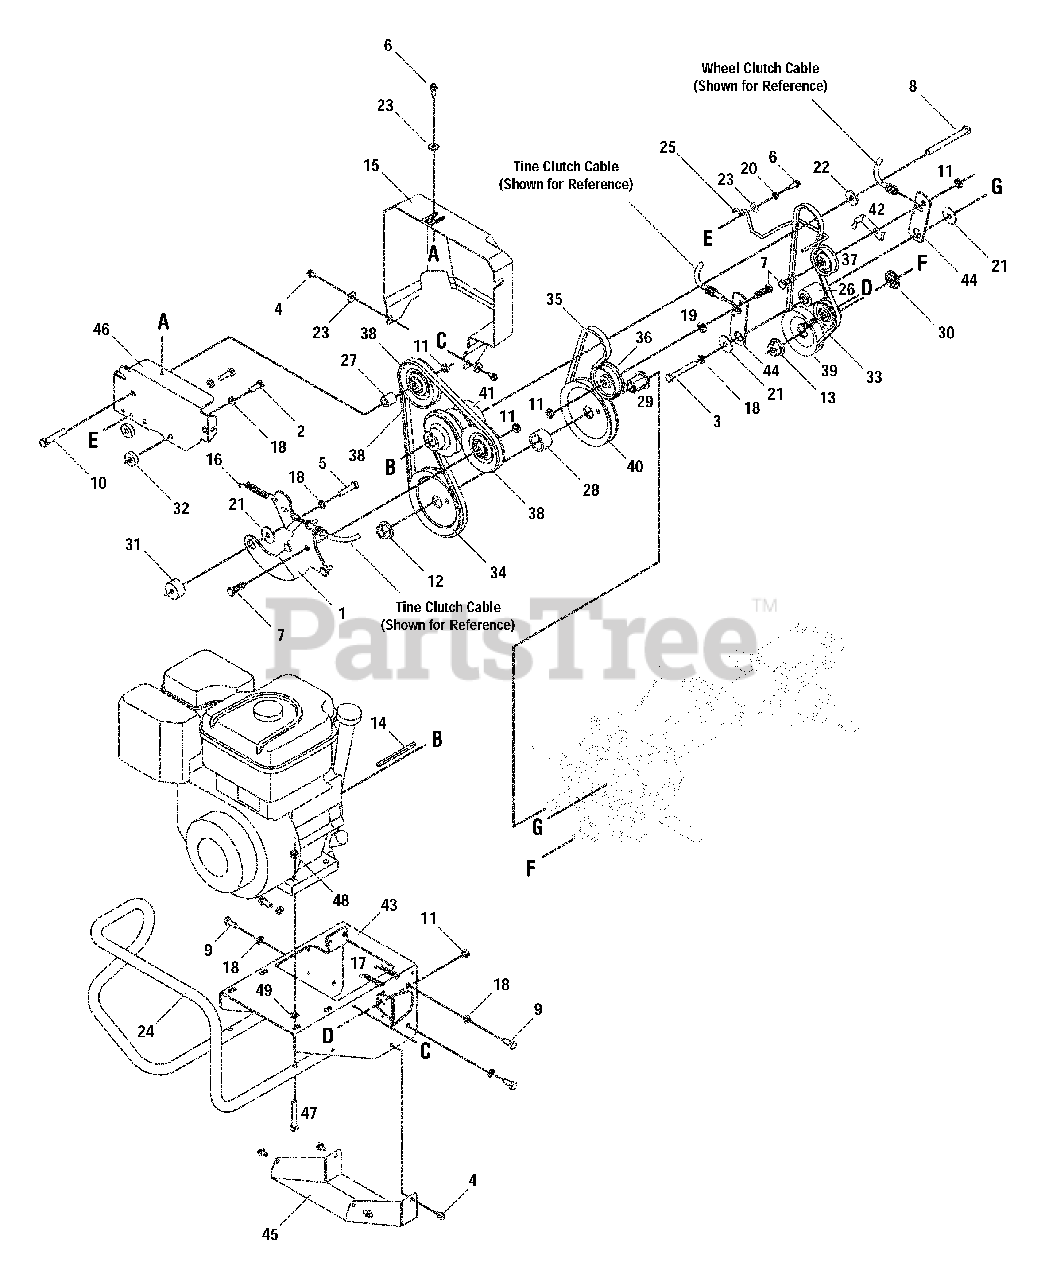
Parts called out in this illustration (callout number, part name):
1	Bracket Assembly, Clutch
2	Hex Screw, 5/16-24, 1.00, Gr5
3	Hex Screw, 5/16-18, 2.50, Gr5
4	Screw, Self-tapping, 1/4-20, 0.500
5	Hex Screw, 5/16-24, 1.50, Gr5
6	Screw, Self-tapping, 1/4-20, 0.750
7	Hex Screw, 3/8-16, 1.25, Gr5
8	Hex Screw, 3/8-24, 3.75, Gr5
9	Hex Screw, 5/16-18,.75, Gr5
10	Hex Screw, 3/8-16, 2.00, Gr5
11	Nut, Jam Lock, 3/8-16, Gr2
12	Nut, Flange, 9/16-18, Gr2
13	Nut, Flange, 7/16-20, Gr2
14	Key, Sq,.1875 x 3.625
15	Cover, Belt
16	Spring, Extension,.38 x 3.25
17	Extension Spring.35 x 1.14
18	Washer, Lock, 5/16, Regular Duty
19	Washer, Flat,.375 x.738 x.063
20	Washer, Lock, 1/4, Regular Duty
21	Washer, Flat,.330 x 1.25 x.06, Ht
22	Washer, Bell,.396 x 1.140 x.095
23	Washer, Flat,.260 x.720 x.060
25	Keeper, Belt
26	Spacer,.330 x 1.25 x 1.605
27	Spacer,.390 x.750 x.812
28	Spacer, 1.030 x 1.375 x.830 Lg
29	Hub, Pulley, Input, 5/8
30	Hub, Pulley, Input, 1/2
31	Spacer,.330 x 1.250 x.845
32	Spacer.33 x 1.0 OD
33	V-belt
34	Belt
35	Belt
36	Pulley, Idler, Flat w/ Flange 2.25 OD
37	Pulley, Idler, Flat 1.88 OD
38	Pulley, Idler, V-type 3.5 Dia
39	Pulley, 3l, 3.088 Eff Dia
40	Pulley, 4l, 5.0 Eff Dia
41	Pulley, Engine, 3 Belt
42	Keeper, Belt, Idler
43	Frame, Engine
44	Bracket, Clutch, Forward
45	Cover, Bottom, Frame, Engine
46	Bracket, Mounting, Cover, Belt
47	Hex Screw, 5/16-18, 2.25, Gr5
48	Nut, Hex Lock, 5/16-18, Gr5, Nylon
49	Nut, Speed,.3125 ID
